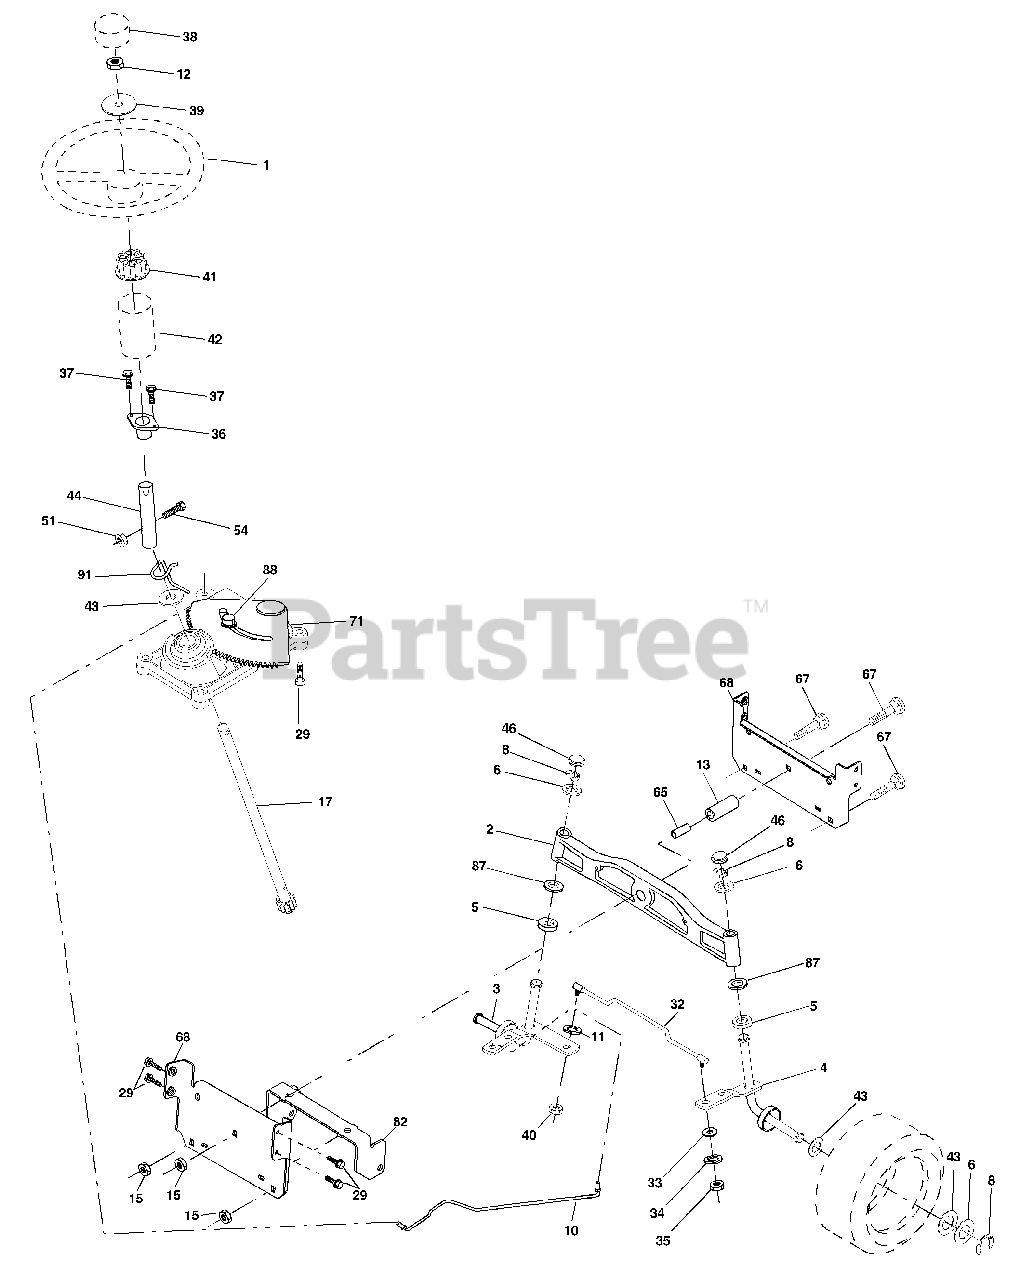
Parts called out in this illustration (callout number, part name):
1	Wheel Steering
2	Axle Asm Cast Iron LT
3	Spindle Asm LH
4	Spindle Asm RH
5	Bearing Race Thrust Harden
6	Washer 25/32 X 1-5/8 X 16 Ga
8	Ring Klip #t5304-75
10	Link Drag
11	Washer Lock Hvy Hlcl Spr 3/8
12	Nut Hex Jam Toplock 1/2-20 UNF
13	Spacer Brg. Axle Front
15	Nut Hex Flange Lock
17	Shaft Asm. Steering
29	Screw 3/8-16x.75
32	Rod Tie
33	Washer 11/32 x 3/4 x 16 Ga.
34	Washer Lock Hvy Hlcl Spr 5/16
35	Crownlock Nut 5/16-24
36	Bushing Strg
37	Screw
38	Insert Cap Strg Wh Au
39	Washer 9/16 ID x 1 1/2 OD.11 Ga
40	Lock nut
41	Adaptor Wheel Strg
42	Boot Steering Dash
43	Washer 25/32 X 1 1/4 X 16 Ga
44	Extension Steering Shaft LR/LT
46	Cap Spindle Fr Top Blk
51	Nut Crownlock 1/4-28
54	Bolt Hex 1/4-28 UNF x 1-1/4 Ga 8
65	Brace Axle
67	Bolt Rdhd Sq 3/8-16 Unc x 2-1/4
68	Axle, Brace
71	Steering Asm.
82	Bracket Susp. Chassis Front
87	Washer Flat .781 x 1-1/2 x .14
88	Bolt Shoulder 7/16-20 Unc
91	Clip Steering
